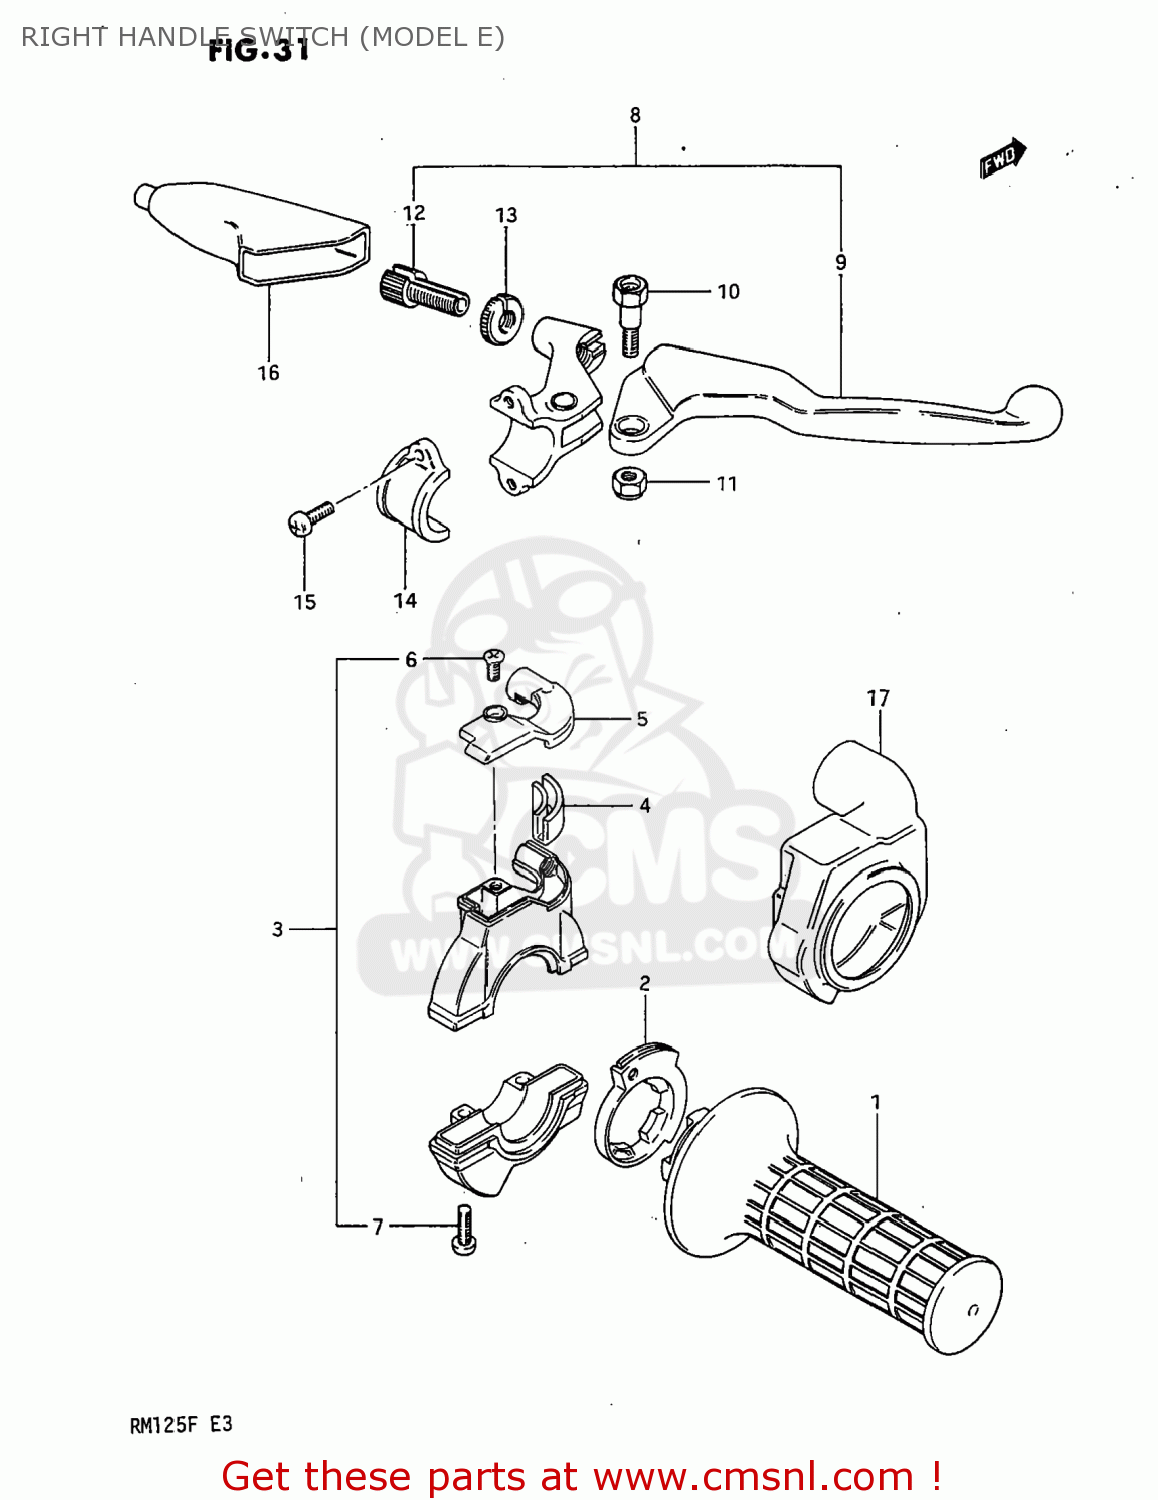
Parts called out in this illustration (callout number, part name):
1	GRIP,THROTTLE
2	ROTOR,THROTTLE GRIP
3	CASE ASSY,THROTTLE
4	GUIDE PIECE,THROTTLE
5	COVER,THROTTLE CASE
6	SCREW
7	SCREW
8	LEVER ASSEMBLY,BRAKE
9	LEVER,BRAKE
10	BOLT,LEVER
11	NUT 6MM
12	ADJUSTER,CABLE
13	NUT,CABLE ADJUSTER
14	BRACKET,CLUTCH LEVER HOLDER
15	SCREW
16	COVER,CLUTCH LEVER
17	COVER,THROTTLE CASE
